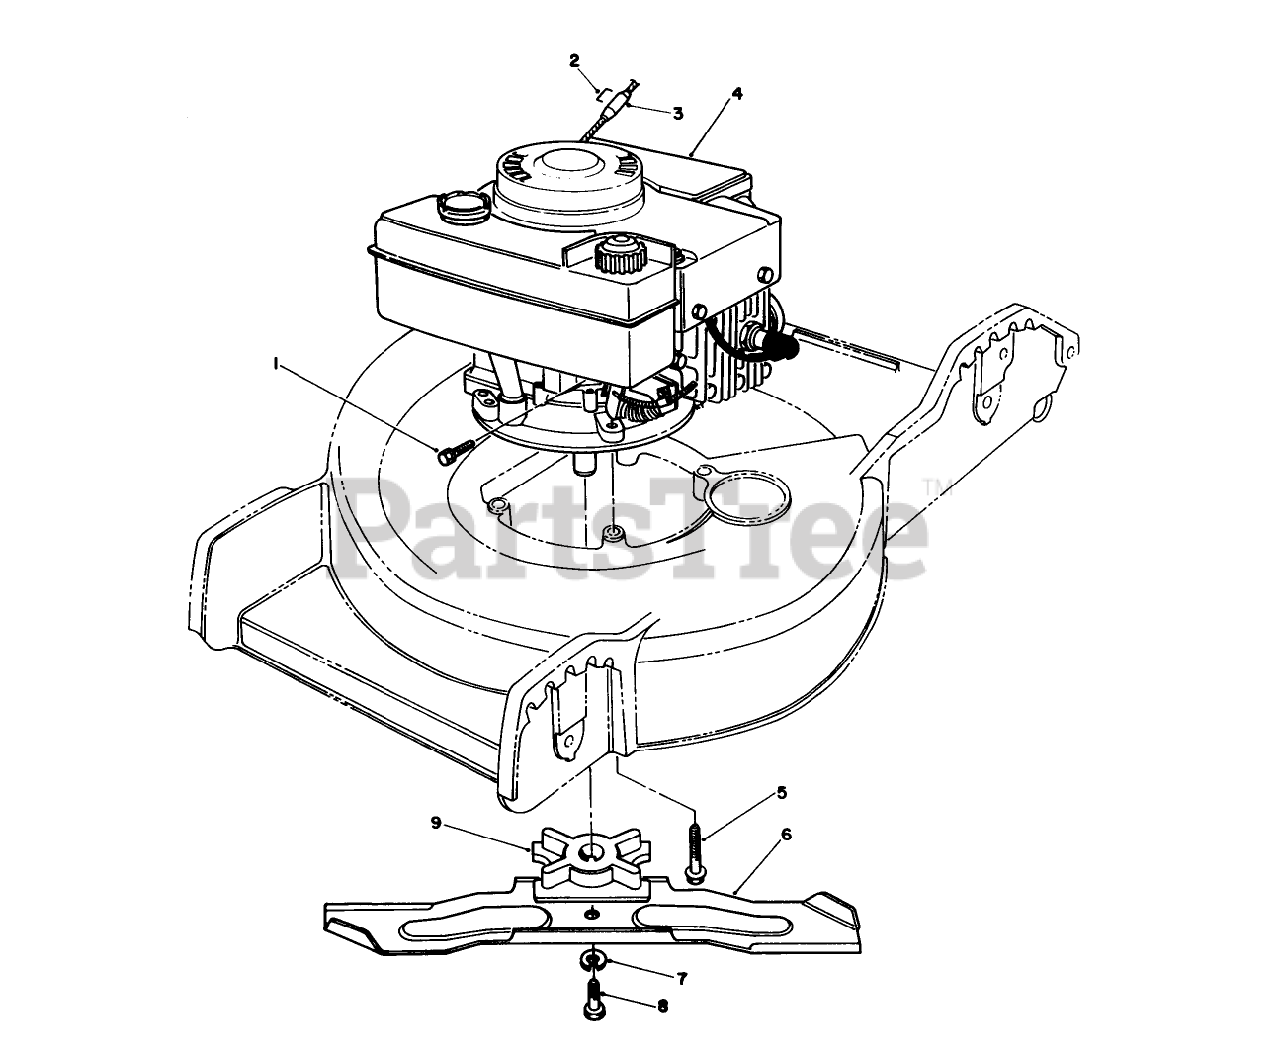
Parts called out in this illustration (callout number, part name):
1	SCREW-HH
2	Staple
3	Stop-Rope
5	3/8-16 X 2 CAPSCREW
6	Blade
7	WASHER-LOCK
8	SCREW-HH
9	BLADE RETAINER
